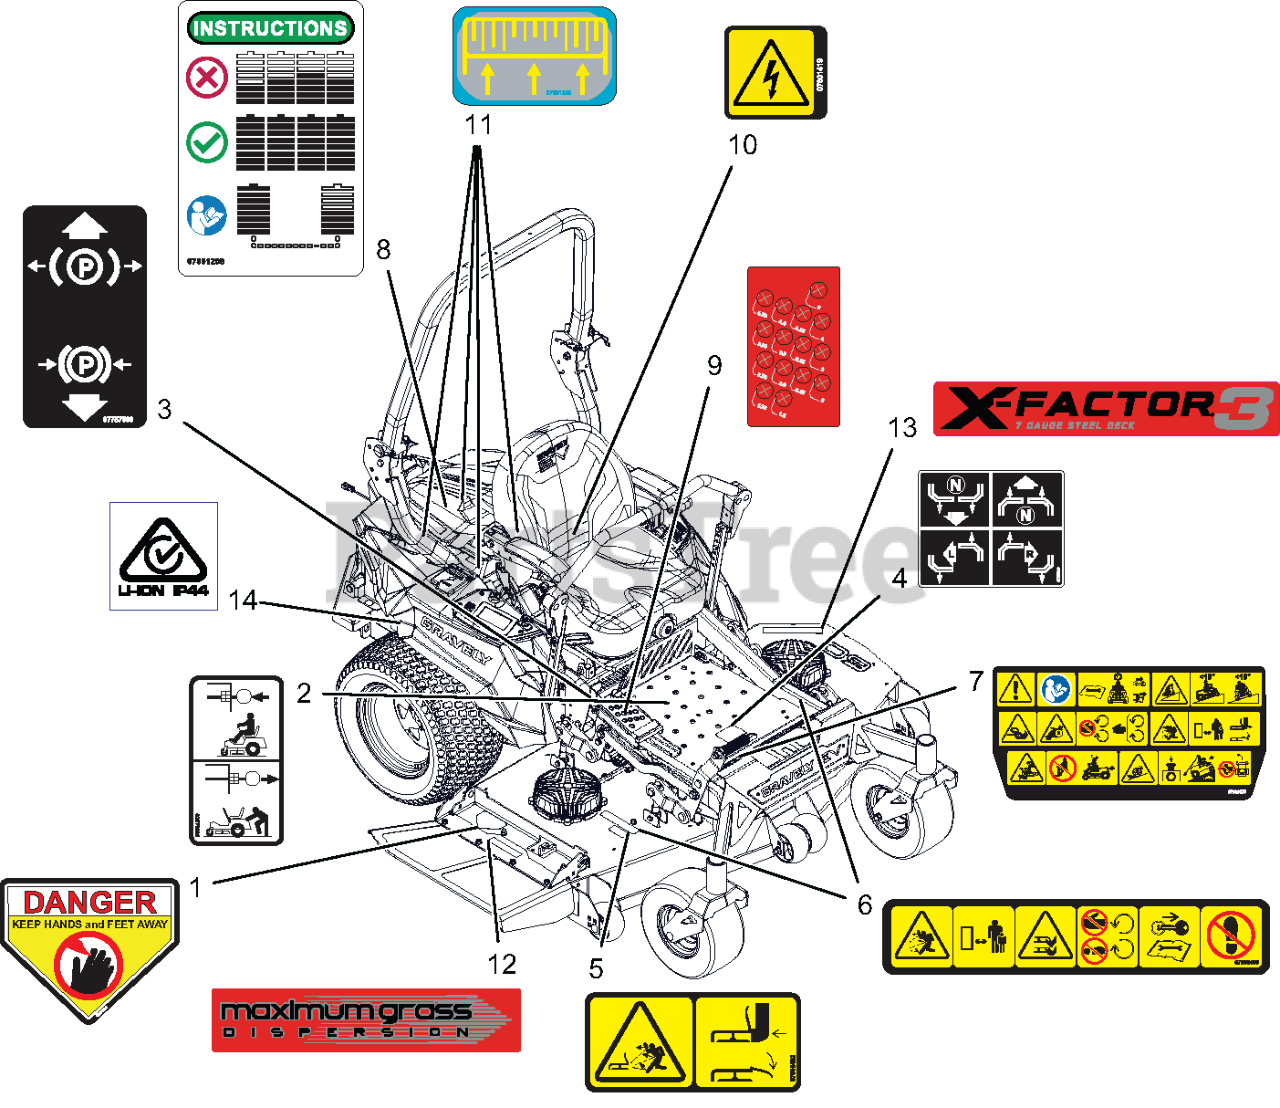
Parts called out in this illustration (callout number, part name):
1	DECAL, DANGER
2	DECAL, TRANSMISSION DISCONNECT
3	DECAL, PARKING BRAKE LEVER
4	DECAL, INSTRUCTIONAL-STEERING
5	DECAL, SAFETY - DECK GUARDING
6	DECAL, DECK SAFETY
7	DECAL, MAIN SAFETY
8	DECAL, BATTERY BALANCE
9	DECAL, HEIGHT OF CUT
10	DECAL, SAFETY - DANGER
11	DECAL, BATTERY INSTALL DIRECTION
12	DECAL, DECK - MAX GRASS
13	DECAL, DECK - X-FACTOR 3
14	DECAL, LI-ION IP44
